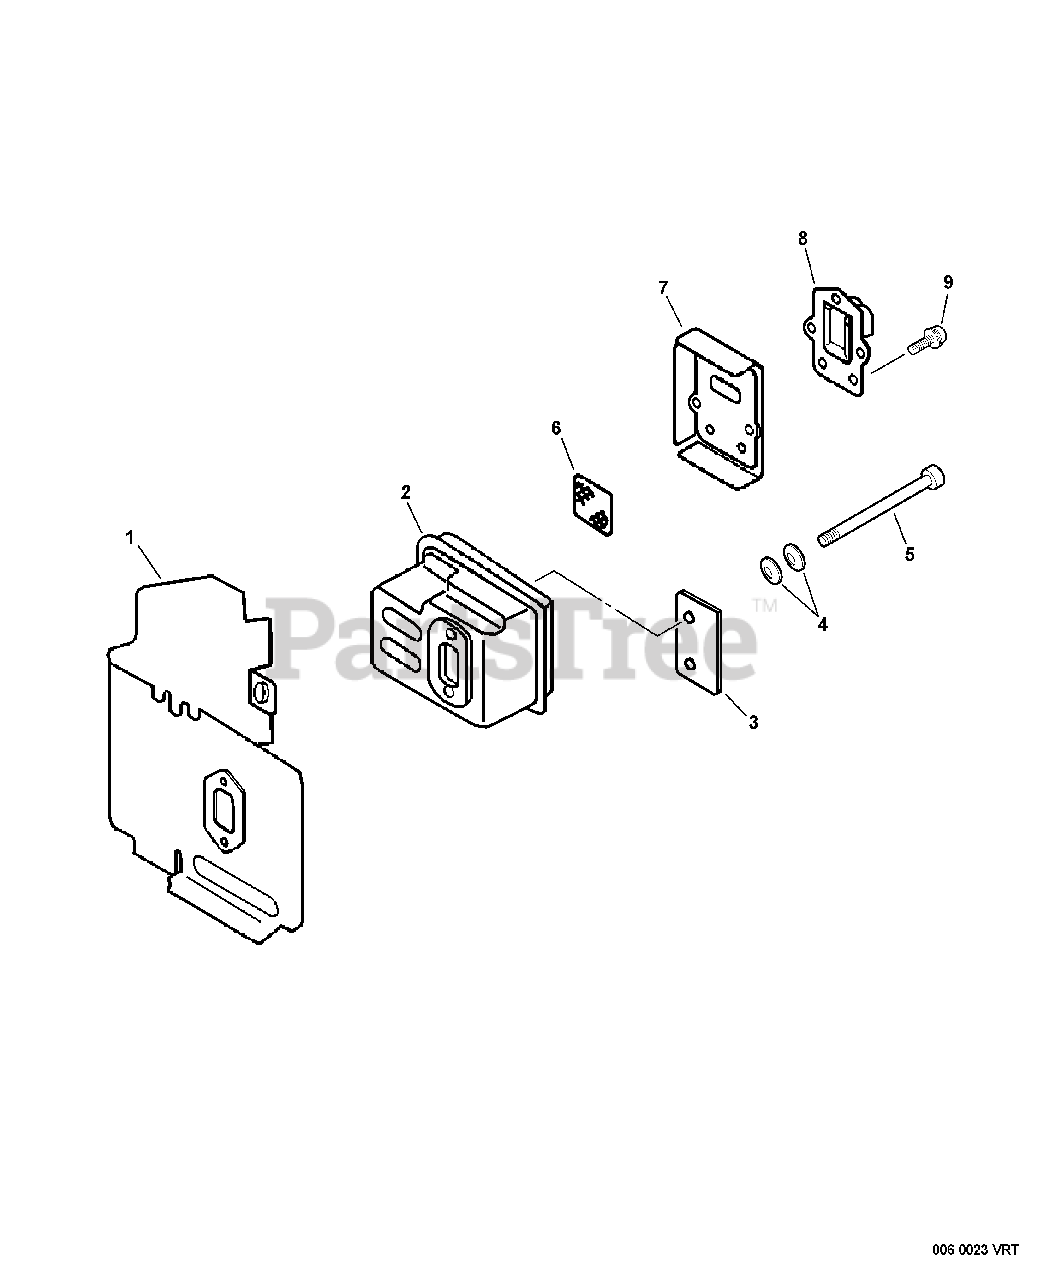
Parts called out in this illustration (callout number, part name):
1	SHIELD, EXHAUST
2	MUFFLER
3	PLATE, EYE
4	CONICAL WASHER
5	BOLT 5×55
6	SCREEN, SPARK ARRESTER
7	GASKET, EXHAUST
8	GUIDE, EXHAUST
9	SCREW 4×12
